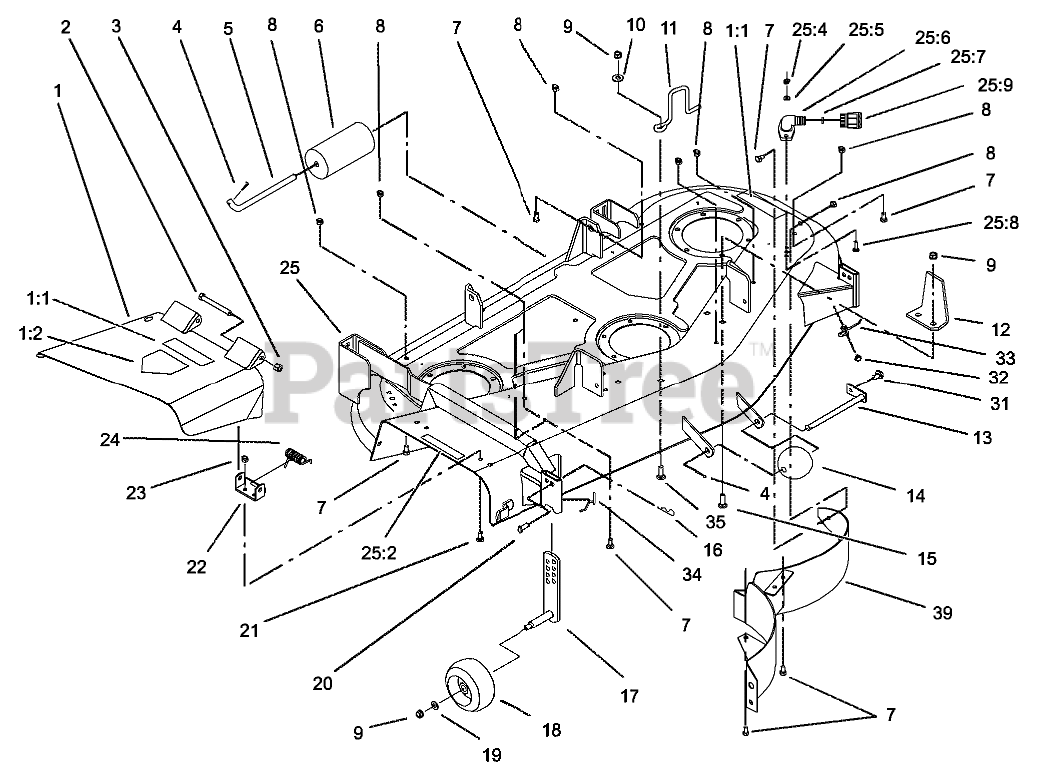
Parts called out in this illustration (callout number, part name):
1	Deflector ASM (only on: 78370, 78375)
1	Deflector ASM (only on: 78452)
1:1	Decal-Danger (only on: 78452)
1:1	Decal-Danger (only on: 78370, 78375)
1:2	Decal-Danger (only on: 78370, 78375)
1:2	Decal-Danger, Int-l (only on: 78452)
2	SCREW-HH
3	NUT-HEX
4	PIN-COTTER
5	SHAFT-ROLLER, REAR
6	ROLLER-DECK
7	Screw-HH (only on: 78370)
7	Screw-HH (only on: 78452)
8	Nut-Lock, NI (only on: 78370)
8	Nut-Lock, NI (only on: 78452)
9	NUT-LOCK, NI
10	WASHER
11	GUIDE-BELT
12	Bracket Guide
13	SHAFT ASM
14	ROLLER
15	BOLT-CARR
16	PIN-HAIR
17	GAGE-WHEEL
18	WHEEL-GAGE
19	WASHER-FLAT
20	PIN-CLEVIS
21	SCREW-CARR
22	BRACKET-PIVOT
23	NUT-LOCK, NI
24	SPRING
25	Deck ASM (only on: 78452)
25	Deck ASM (only on: 78370, 78375)
25:2	Decal-Caution (only on: 78370, 78375)
25:2	Decal-Danger (only on: 78452)
25:4	Nut-Lock, NI (only on: 78370, 78375)
25:5	Washer-Flat (only on: 78370, 78375)
25:6	Fitting-Washout (only on: 78370, 78375)
25:7	O-Ring (only on: 78370, 78375)
25:8	Screw-CARR (only on: 78370, 78375)
25:9	Connector-Hose (only on: 78370, 78375)
31	SCREW-HWHTF
32	SCREW-HHFTF
33	SPRING-GAGE WHEEL, LH
34	SPRING-GAGE WHEEL, RH
35	SCREW-CARR
39	Baffle (only on: 78370)
